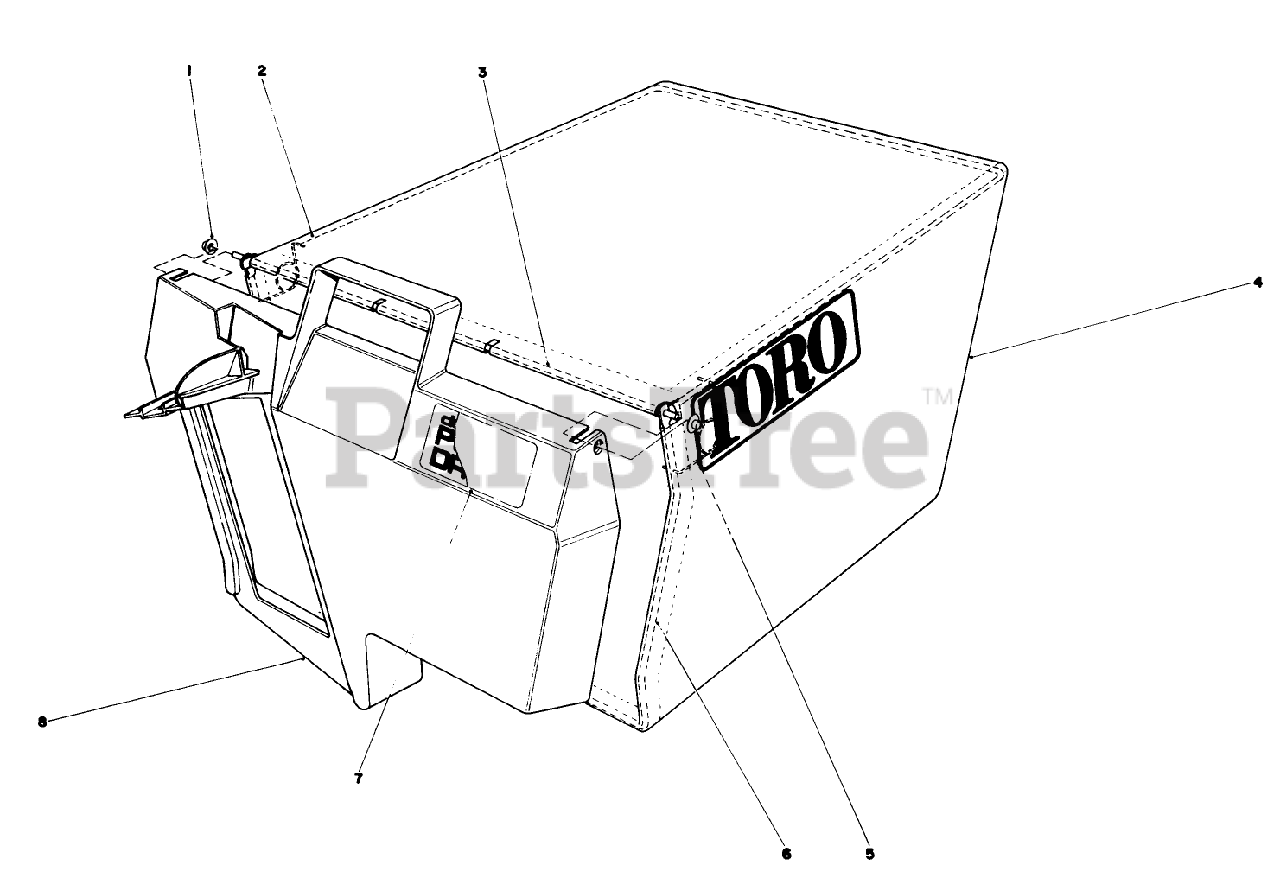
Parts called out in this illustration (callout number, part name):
1	Push Nut
3	HINGE-DOOR, BAG
5	SPRING
6	FRAME-BAG
